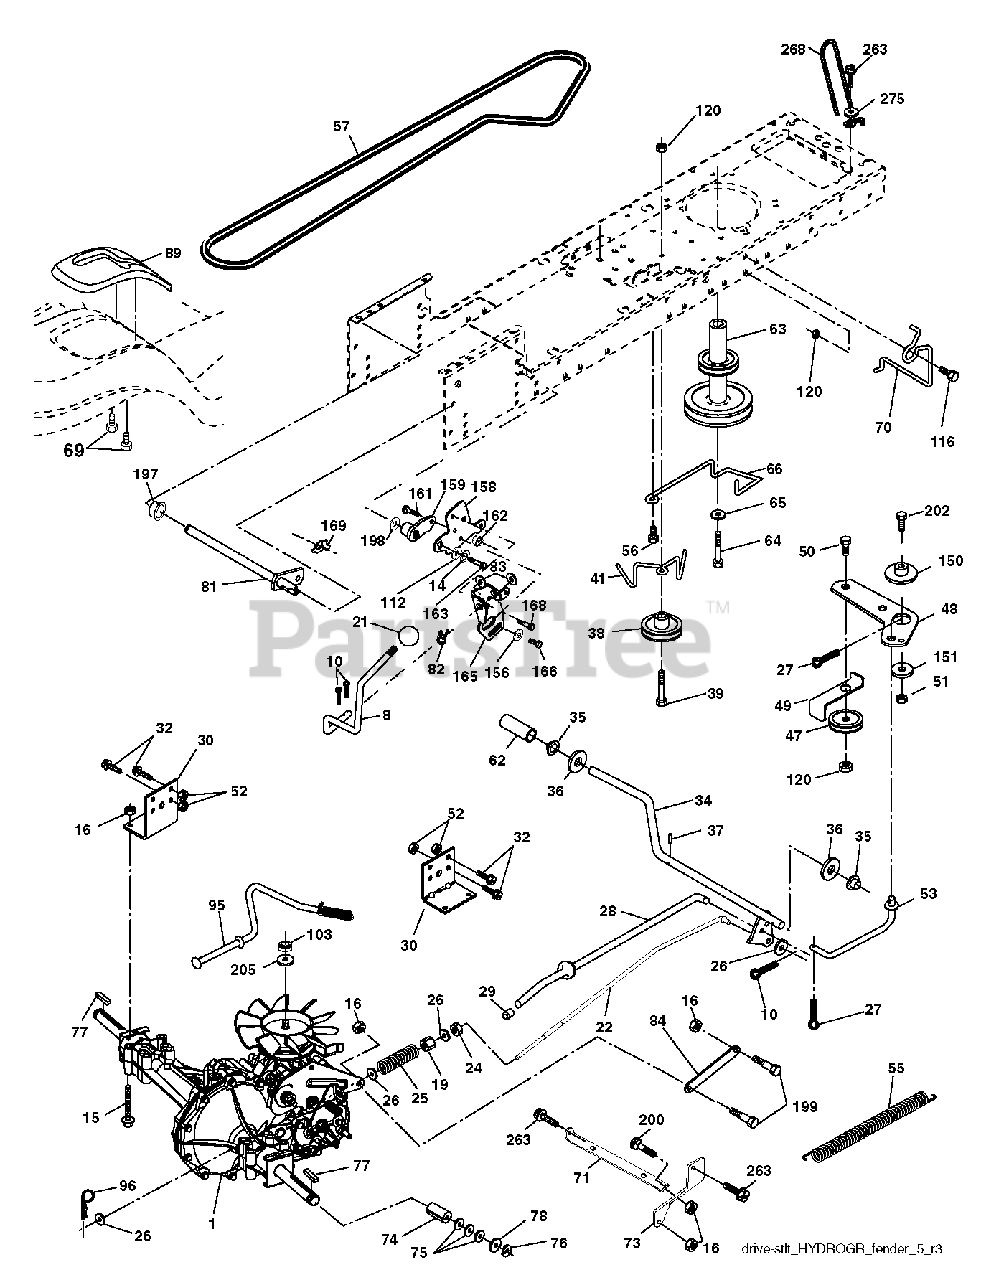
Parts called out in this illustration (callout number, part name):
8	ROD SHIFT FENDER ADJUST LT
10	PIN COTTER
14	LOCKWASHER
15	BOLT HEX 5/16-18 GR 5
16	NUT.71038.31-18.HEX.NYLOCK
19	NUT
21	KNOB T (1/2-HOLE)
22	ROD BRAKE HYDRO
24	NUT
25	SPRING ROD LT
27	COTTER PIN
28	ROD, PARKING BRAKE
29	PLUNGER CAP
30	BRKT, MOUNT TRNSAXLE
32	BOLT
34	SHAFT, FOOT PEDAL
35	BEARING.NYLON
36	WASHER LT
37	DRIVE PIN
38	PULLEY IDLER COMPOSITE
41	KEEPER, BELT IDLER
47	IDLER PULLEY
48	BELLCRANK, CLUTCH
49	RETAIN BELT
50	BOLT.3/8-16X1.50
51	LOCKNUT
52	LOCKNUT
53	LINK.CLUTCH.7.66.2005
55	SPRING, RETURN LT
56	SCREW.3/8-16
57	DRIVE BELT, LTH & YTH TRACTORS
62	PEDAL COVER T
63	ENGINE PULLEY
64	BOLT HEX 7/16-20X4-1/4"
65	LOCKWASHER
66	KEEPER BELT ENGINE
69	SCREW.HI-LO.CONSOLE
70	KEEPER BELT ENG
71	STRAP TORQUE LH HYDRO
73	STRAP TORQUE RH HYDRO
74	SPACER AXLE
76	E-RING LT
77	SQUARE KEY
81	SHAFT ASM CROSS TAPERED
82	SHIFT SPRING
83	WASHER
95	CONTROL ASM. BYPASS HYDRO
96	RETAINER M
103	NUT.HEX.1/2-20
112	WASHER LT
116	BOLT D
120	NUT LOCK FLG 3/8-16 UNC
150	SPACER, RETAINER
151	WASHER 12/32X2X10GA
156	WASHER.SRRTD.5/16
158	BRACKET.SHIFT.MOUNT
159	HUB.SHIFT
161	BOLT
162	NUT.CROWNLOCK.1/4
165	BRACKET.PIVOT.LEVER
168	BOLT.SHOULDER.5/16-18X
169	PLATE.FASTENING.CROSS.SHAFT
197	NYLINER SNAP 5/8" ID
198	WASHER.NYL.7/8IDX.105"HYD CR
199	BOLT SHOULDER 5/16-18 UNC
200	BOLT
202	BOLT
205	WASHER
263	SCREW, 3/8-16X3/4
275	WASHER
